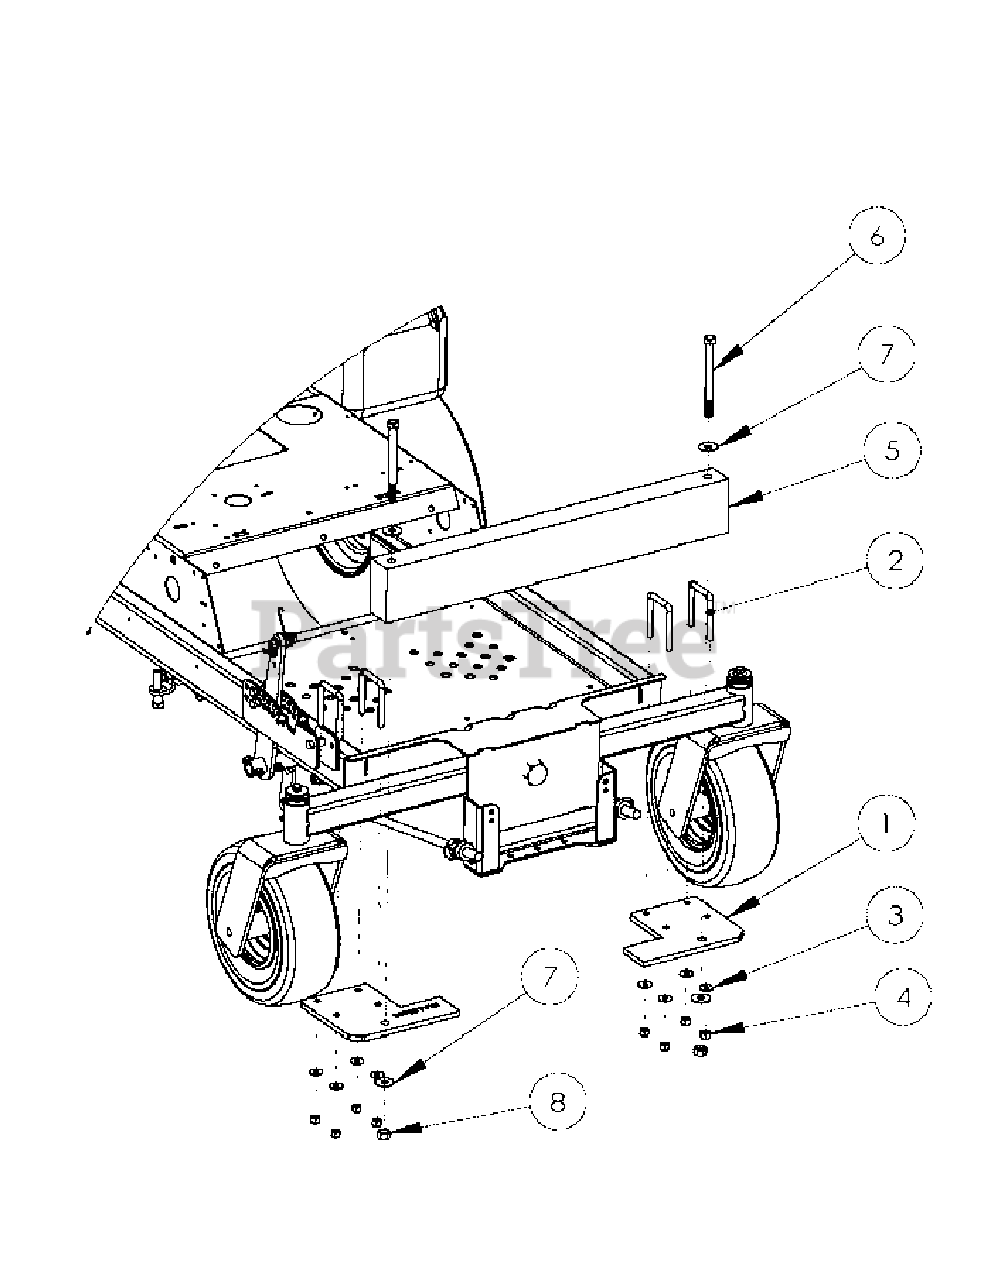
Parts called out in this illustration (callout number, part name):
1	48"-60" RECON WEIGHT BRACKET
3	FLAT WASHER 5/16"
4	HEX NUT, NYLON INSERT 3/8"-16
5	BAR, WEIGHT
6	CAP SCREW, 1/2"-13 X 5 1/2" LONG
7	FLAT WASHER 1/2"
8	HEX NUT, NYLON INSERT 1/2"-13
